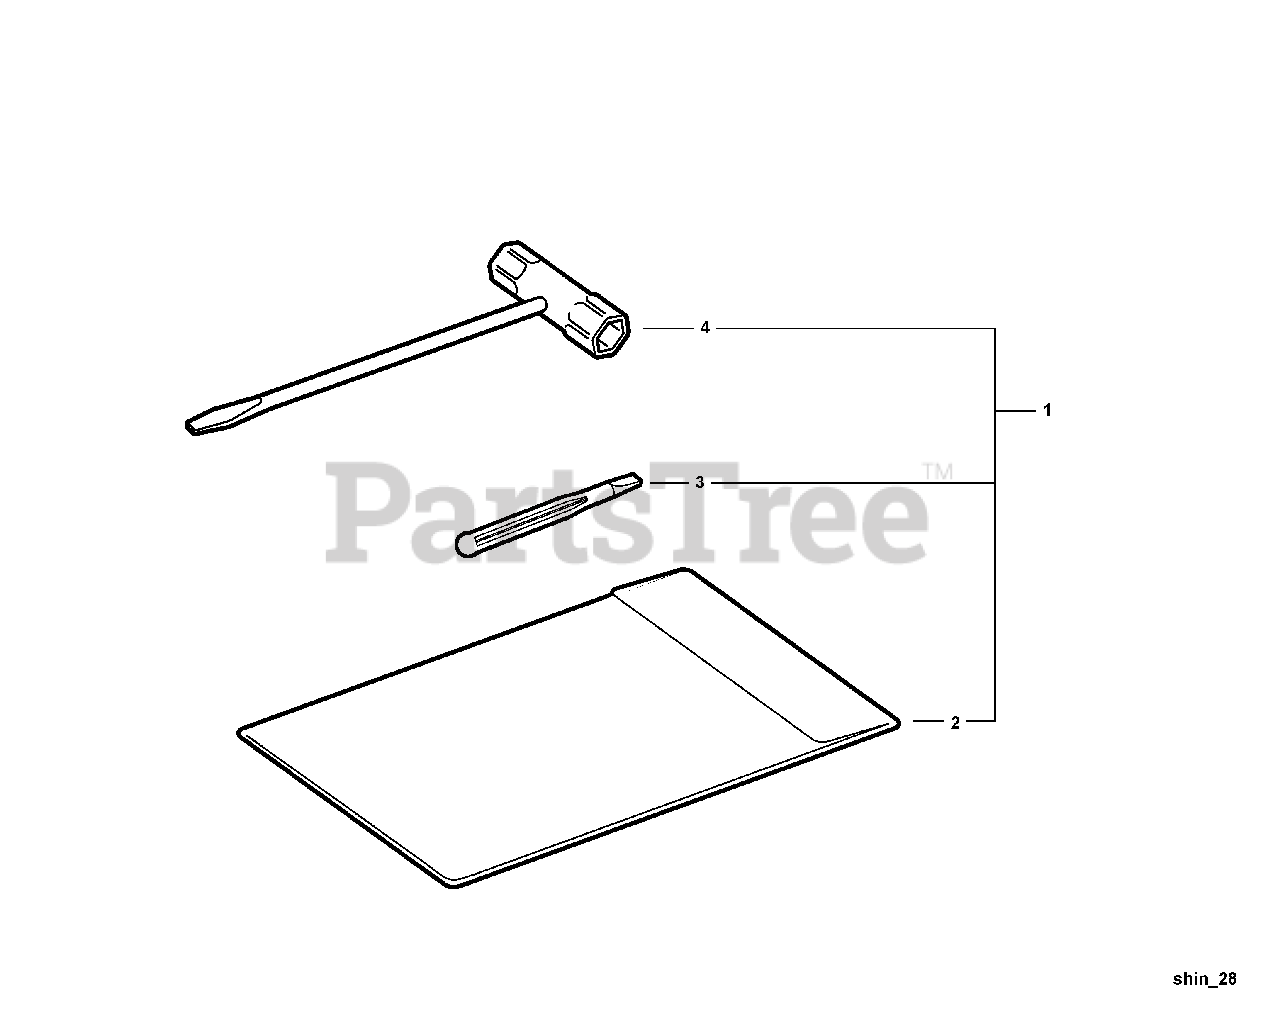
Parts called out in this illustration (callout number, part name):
1	TOOL KIT
2	BAG, TOOL
3	SCREWDRIVER - PLASTIC
4	T-WRENCH - 13X19mm
